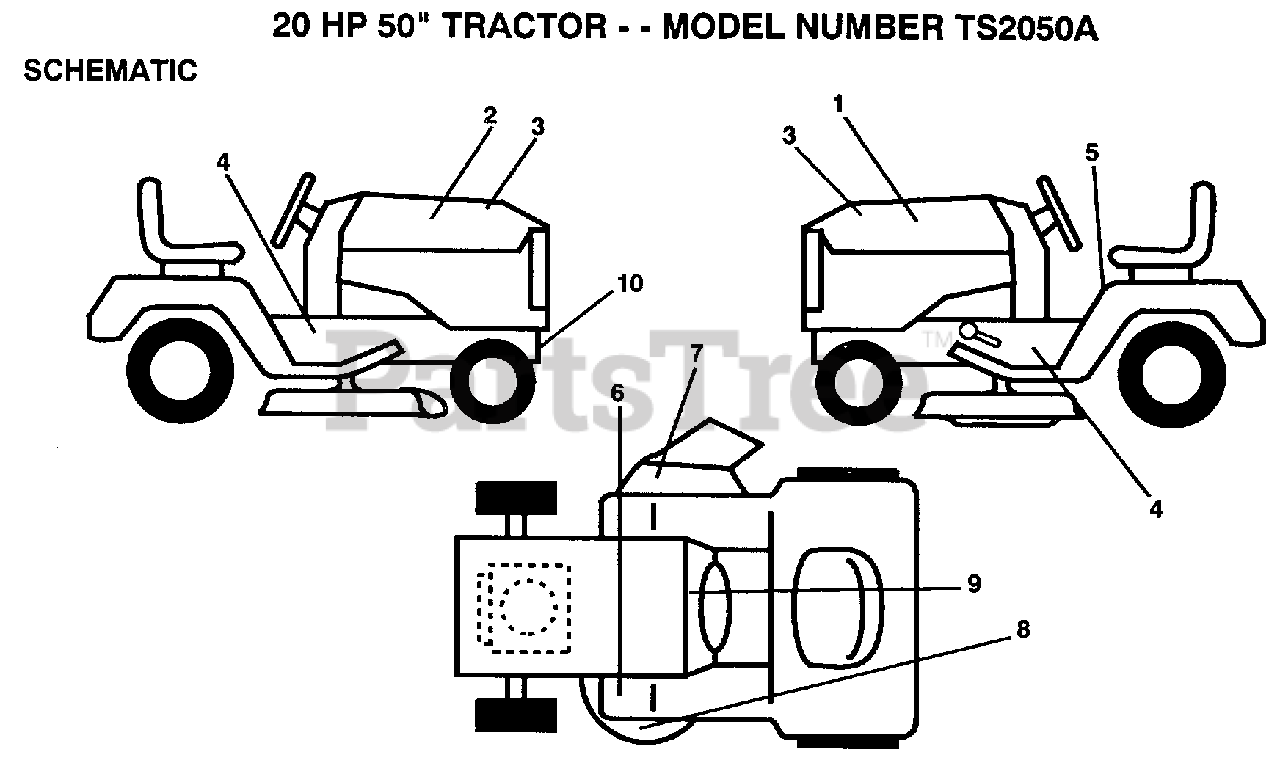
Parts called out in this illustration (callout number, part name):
5	DECAL
7	DECAL WARING
8	DECAL INSTRUCTION CAUTION
